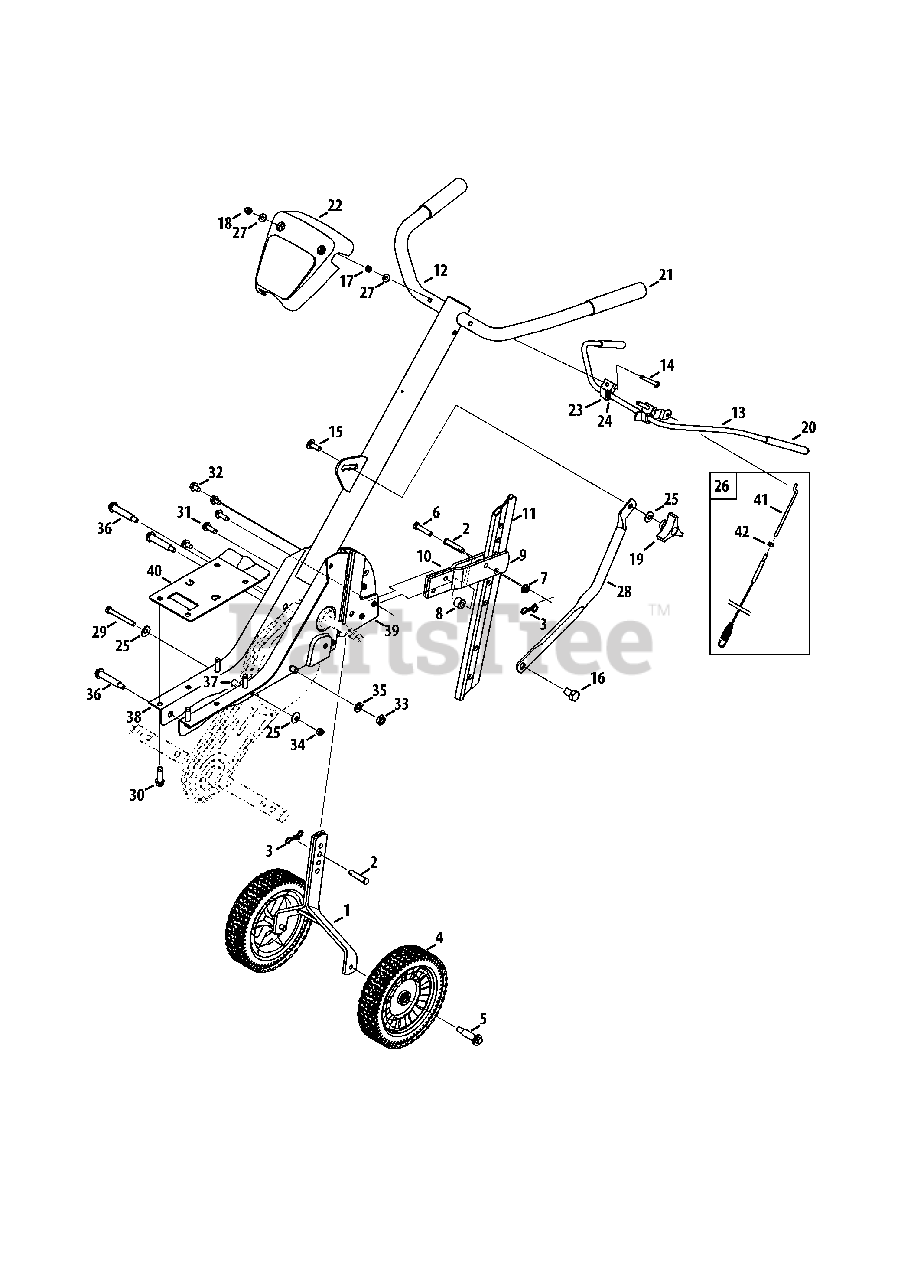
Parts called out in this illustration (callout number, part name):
1	Wheel Bracket Assembly
2	Clevis Pin, .375 x 1.75
3	Bow Tie Cotter Pin
4	Complete Wheel Assy. 8 x 1.75
5	Shoulder Screw, .496 x 1.445 3/8-16
6	Hex Head Screw, 5/16-18 x 1.50
7	Nut, 5/16-18, Flange Lock
8	Spacer, .325 ID x .75 OD x .520
9	Tail Bracket, LH
10	Tail Bracket, RH
11	Depth Bar
12	Complete Handle Assembly
13	Clutch Bail
14	Hex Head Screw, 1/4-20 x 2.25
15	Carriage Screw, 5/16-18 x 1.00
16	Hex Lock Screw, 1/2-20 x .750
17	Jam Nut, 1/4-20
18	Nut, 1/4-20, Lock
19	Handle Knob
20	Grip, Clutch Bail
21	Grip, Handle
22	Handle Cover
23	Clutch Bail Holder
24	Flat Washer, .385 x .62 x .063
25	Bell Washer, .340 x .872 x .060
26	Forward Clutch Cable
27	Flat Washer, .271 x .630 x .065
28	Handle Brace
29	Hex Head Screw, 5/16-18 x 2.75
30	SEMS Screw, 3/8-16
31	Self-Tapping Screw, 5/16-18 x 1.00
32	Self-Tapping Screw, 5/16-18 x .625
33	Jam Nut, 7/16-20
34	Nylon Hex Lock Nut, 5/16-18
35	Lock Washer, 7/16
36	Shoulder Screw, .475 x 2.11 5/16-18
37	Spacer, .47 OD x .96
38	Frame, RH
39	Frame, LH
40	Engine Mounting Plate
41	Z-Fitting (incl. Ref 42)
42	Jam Nut
